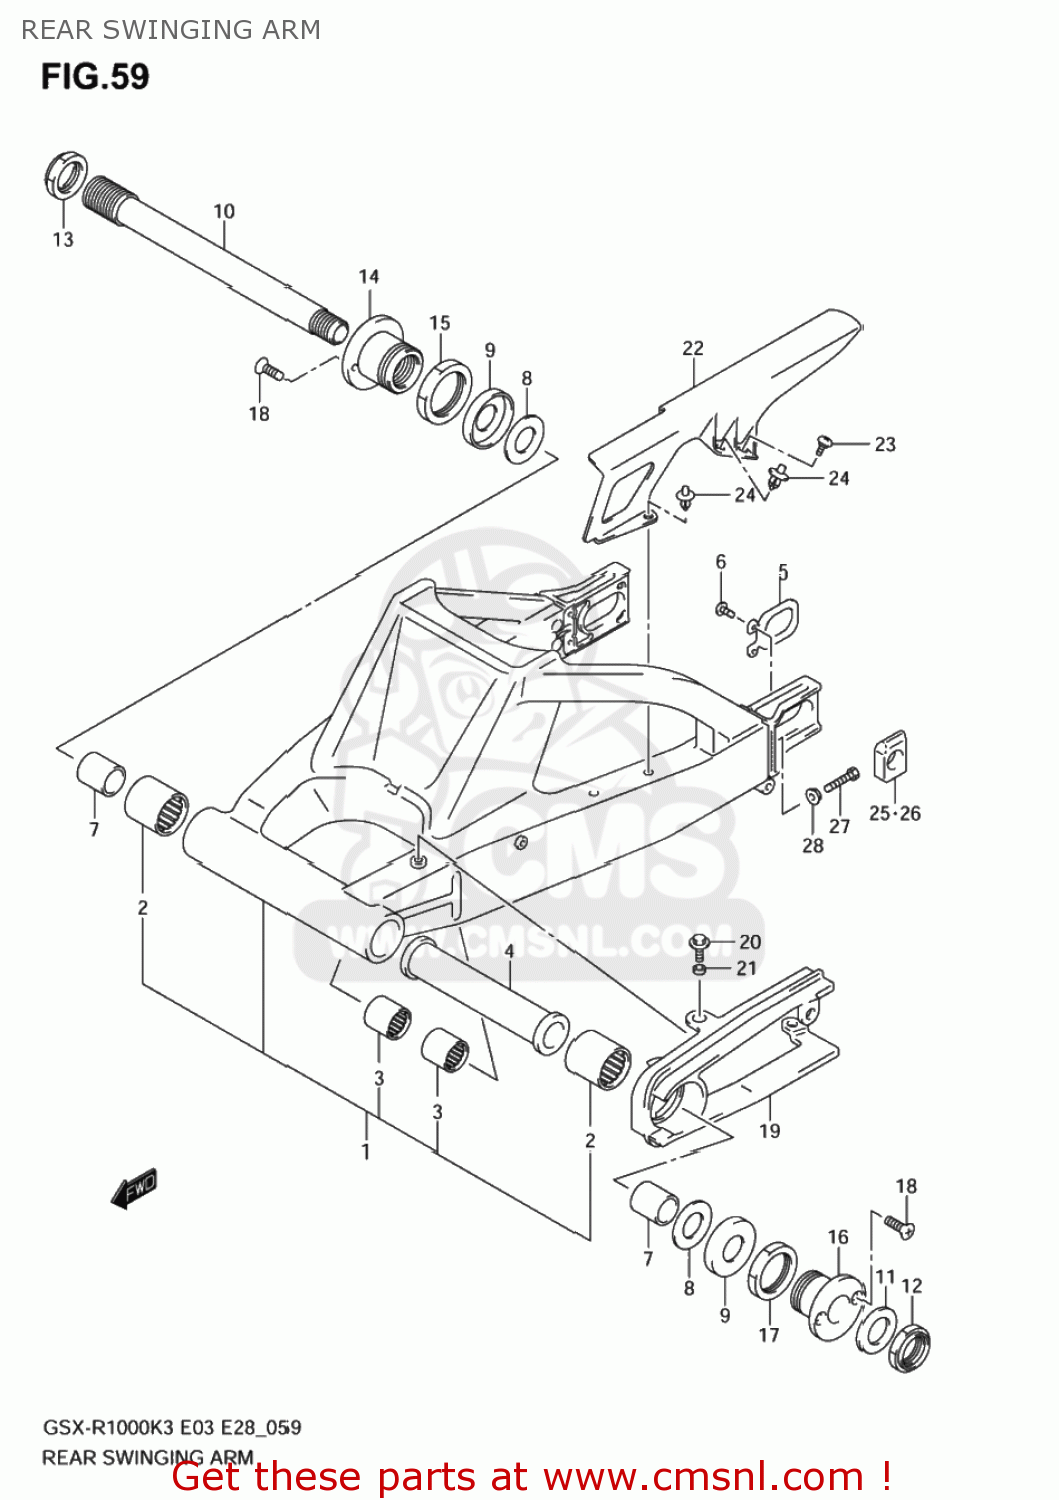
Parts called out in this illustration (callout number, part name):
1	SWINGINGARM ASSY,RR
2	BEARING(30X40X25)
3	BEARING(17X24X20)
4	SPACER,REAR SWING PIVOT,CENTER
5	PLATE,RR SWING ARM BRKT
6	SCREW(6X16)
7	SPACER,REAR SWING ARM PIVOT
8	WASHER
9	DUST SEAL,RR SWGARM PIVOT
10	SHAFT,RR SWINGINGARM PIVOT
11	WASHER(25.2X42X3.2)
12	NUT
13	NUT,RR SWGARM PIVOT BOLT
14	BOSS, RR SWGARM PIVOT, L
15	NUT,RR SWGARM PIVOT BOSS,R
16	BOSS, RR SWGARM PIVOT, L
17	NUT,RR SWGARM PIVOT BOSS,L
18	SCREW
19	BUFFER,CHAIN TOUCH DEFENSE
20	BOLT(6X20)
21	SPACER(6.5X10X2.5)
22	CASE,CHAIN
23	SCREW(6X16)
24	CLIP(BLACK)
25	ADJUSTER,CHAIN,R
26	ADJUSTER,CHAIN,L
27	BOLT(8X50)
28	NUT
